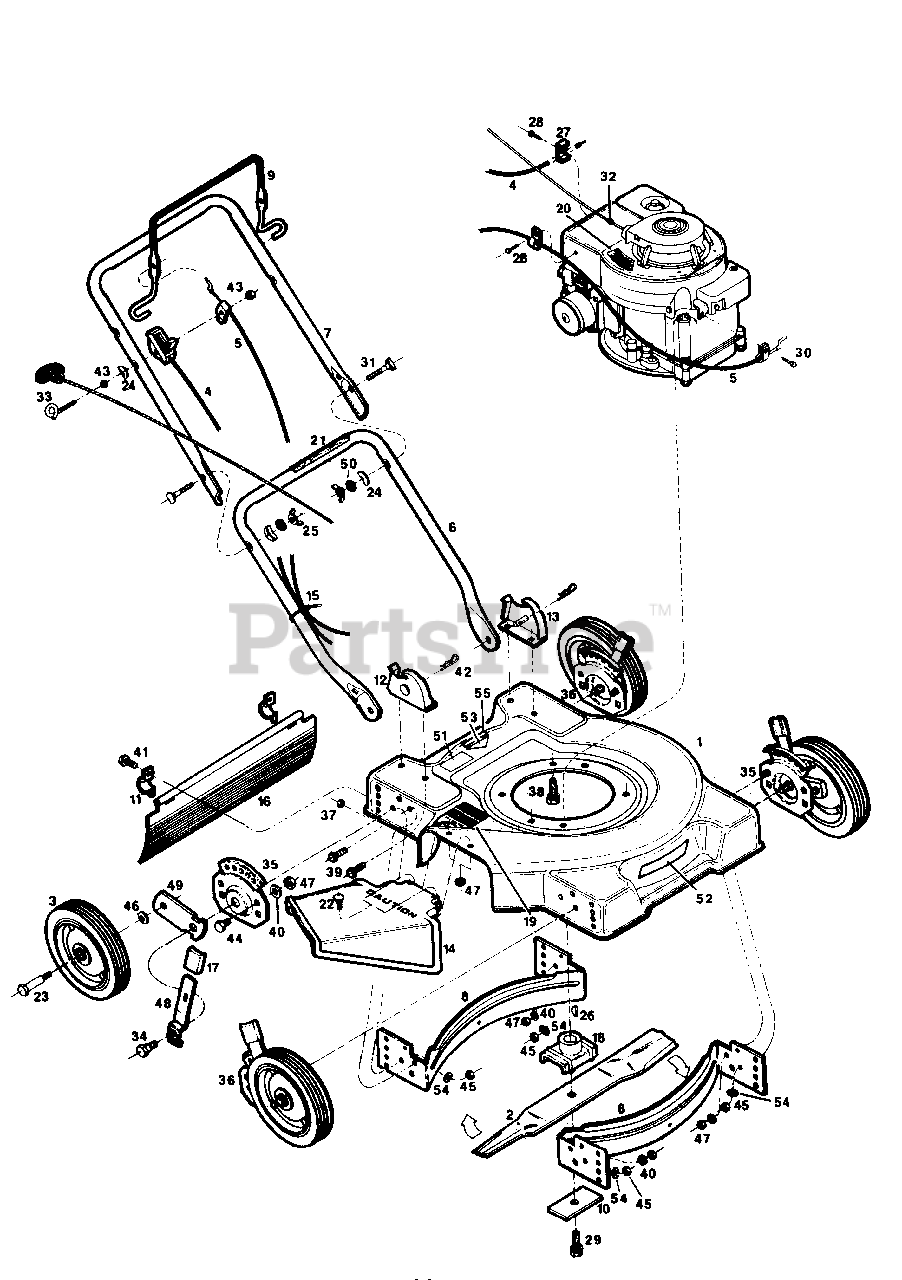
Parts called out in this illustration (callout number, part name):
2	Blade-22"
3	Wheel-8x1.75
4	Control-Throttle with Cable
5	Cable-Engine/Blade Control
6	Handle-Lower
7	Handle-Upper
8	Baffle-Deck
9	Bail-Engine/Blade Control
10	Washer-Blade
11	Clip-Trailing Shield
12	Bracket-Handle, RH
13	Bracket-Handle, LH
14	Deflector-Discharge Chute
16	Shield-Trailing, 22"
17	Tip-Adjusting Lever
18	Adapter-Blade
19	Decal-Danger
20	Decal-Blade Warning
21	Decal-Starting Instructions
22	Bolt-Carriage 1/4-20 x 5/8
23	Bolt-Wheel See 1319PS
24	Washer-Curved, 5/16
25	Wingunt-5/16-18
26	Key-Woodruff #6
27	Clamp-Throttle Cable
28	Screw-Self Tap, #10-5/8
29	Bolt-Blade w/Lockwasher
30	Screw-Hex #10-32 x 3/8
31	Bolt-Curved Head, 5/16-18 x 1-3/4
32	Stop-Rope
33	Eyebolt-Rope Guide
34	Bolt-Shoulder 3/8-16
35	Plate-Adjuster RH Rear, LH Front
36	Plate-Adjuster LH Rear, RH Front
37	Nut-Hex #10-24 Nylok
38	Bolt-Hex 3/8-16 x 7/8 Thd. Form
39	Bolt-Self Tap, 1/4-20 x 1/2
40	Washer-Flat 1/4
41	Bolt-Hex #10-24 x 1/2
42	Hitchpin #3
43	Nut-Hex 1/4-20 Keps
44	Bolt-Hex 1/4-20 x 3/4
45	Nut-Hex 3/8-16 Lock
46	Washer-Belleville
47	Nut-Hex 1/4-20 Lock
48	Setting Lever-Height Adjustment
49	Arm-Wheel
50	Washer-Shakeproof 5/16
51	DECAL, Model Number
52	Decal-Simplicity, Front
53	DECAL, OPEI
54	Washer-Flat 3/8
55	DECAL, "Meets C.P.S.C. Standards"
